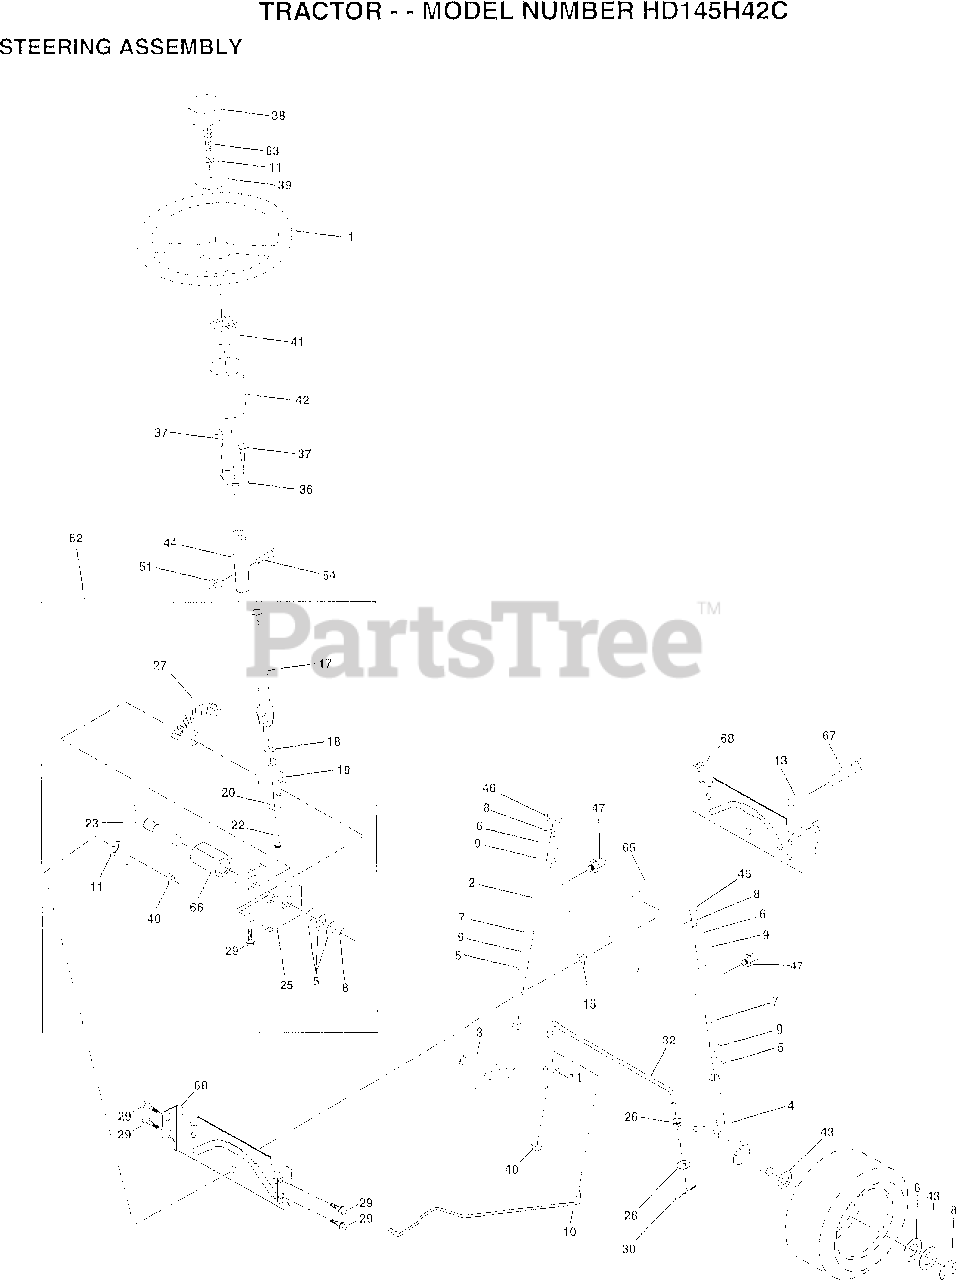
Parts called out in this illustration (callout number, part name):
1	WHEEL STR AYP BLK
2	AXLE ASM
3	SPINDLE.ASM.LH
4	"SPINDLE ASM,RH"
5	WASHER .T
6	WASHER
7	WASHER
8	RING
9	COL. SRTG. BEAR.
10	DRAGLINK-STAMPED
11	LOCKWASHER
13	BEARING AXLE
15	"NUT-LOC,FLANGE LT"
17	SHAFT ASM STEERIN
18	THRUST WASHER
19	SUPPORT.SHAFT
22	SCREW HEX SOC1/4-
25	BRKT-STEERING
26	BUSHING.DRAGLINK
27	GEAR SECTOR
28	WASHER
29	SCREW
30	COTTER PIN
32	TIE ROD
36	BUSHING.STEERING
37	"SCREW-TT,10-32 FL"
38	CAP STEER AYP
39	WASHER T
40	GRIPCO NUT
41	ADAPTER LT
42	BOOT.STEER.PL
43	WASHER
44	EXT SHAFT STEERIN
46	CAP
47	ZERK M
51	NUT
54	BOLT
62	KIT STEERING ASM
63	BOLT
65	SPACER AXLE
66	"BEARING-ARM,PITMA"
67	BOLT
68	BRACE AXLE
